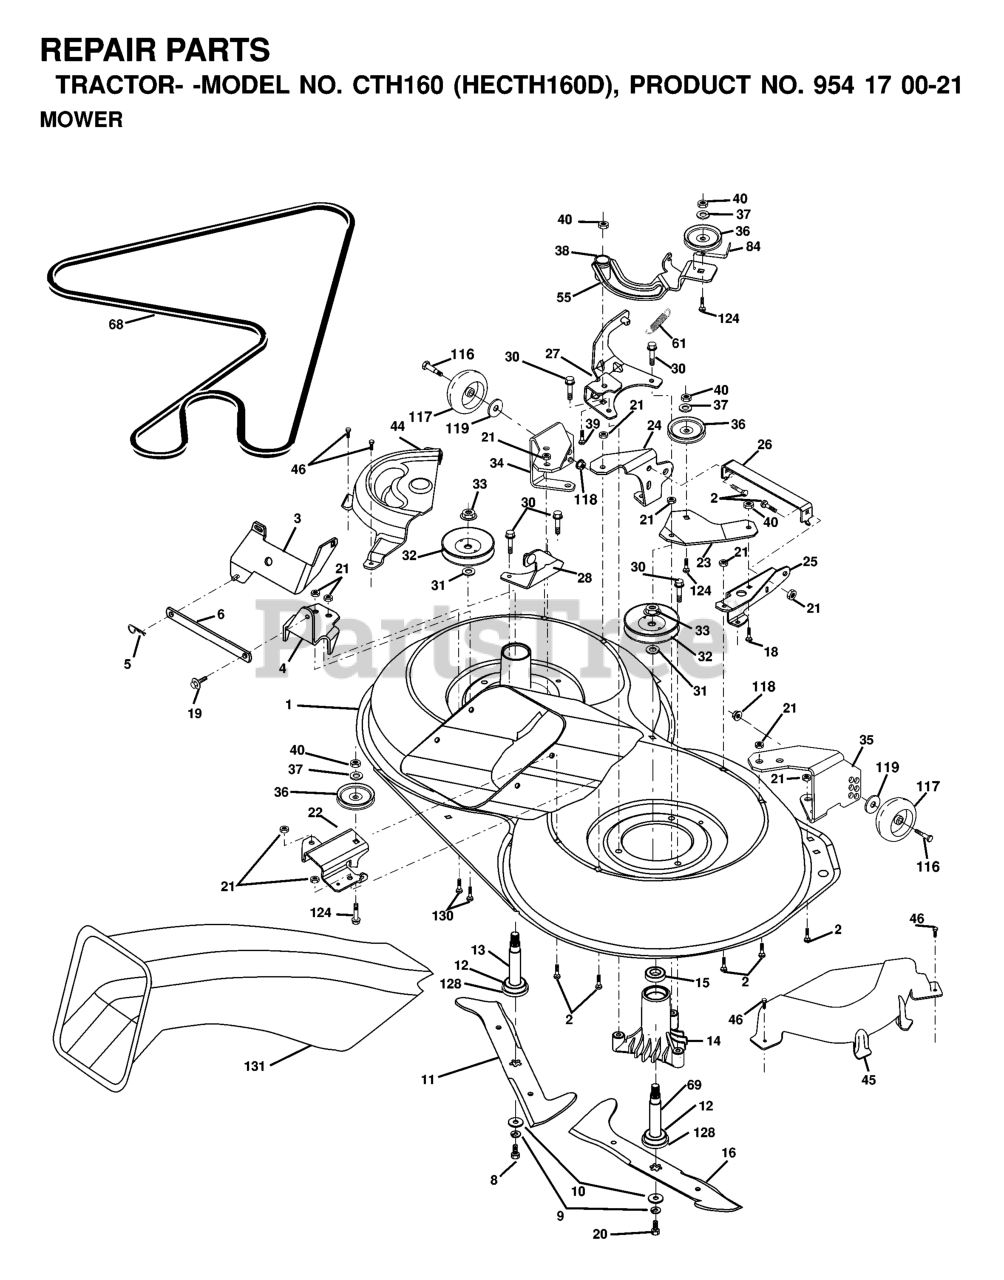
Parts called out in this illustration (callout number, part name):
1	Housing Asm. Mower 107 CRD
2	RP BOLT 5/16-18 X3/4 ZN/YEL GR
5	RETAINER-SPRNG RB
6	BAR.SWAY.92.CRD
8	BLADE BOLT
9	LOCKWASHER
10	WASHER.BLADE
11	BLADE - LH (CTH150)
12	BEARING.BALL.#6204.(MANDREL)
13	SHAFT ASM VENT
14	HOUSING.MANDREL.VENTED (MACHD)
16	BLADE - RH (CTH150)
18	BOLT D
19	BOLT SHD 5/16-18
21	LOCKNUT
22	BRACKET.IDLER.RR.107.CRD
25	BRACKET.SUSPENSION.RF.107.CRD
26	BRACE.SUPT.SUSP.FRT.CRD
28	BRACKET
30	SCREW THDROL ROLLING WASHER HD
31	WASHER
32	PULLEY/MANDREL
33	NUT
34	BRACKET
36	PULLEY.IDLER.4.25
37	WASHER
44	Cover Mandrel Lh 107 CRD
45	MANDREL COVER RH
46	SCREW.1/4-20X5/8
55	ARM.IDLER.107.CRD
56	SPACER RETAINER
61	SPRING.TENSION.BELT
68	HEX-BELT 107 MOWER
69	SHAFT.ASM.W/LWR.BRG.RH.THREAD
84	KEEPER, BELT IDLER
116	BOLT, SHOULDER
117	WHEEL GAGE DONUT
118	LOCKNUT
119	WASHER.5/16.FLAT.STE.STD.
124	BOLT.3/8-16X1.50
128	WASHER FELT
130	BOLT.CARR.SQNK.5/16-18UNC.X3/4
131	CHUTE BAGGER
